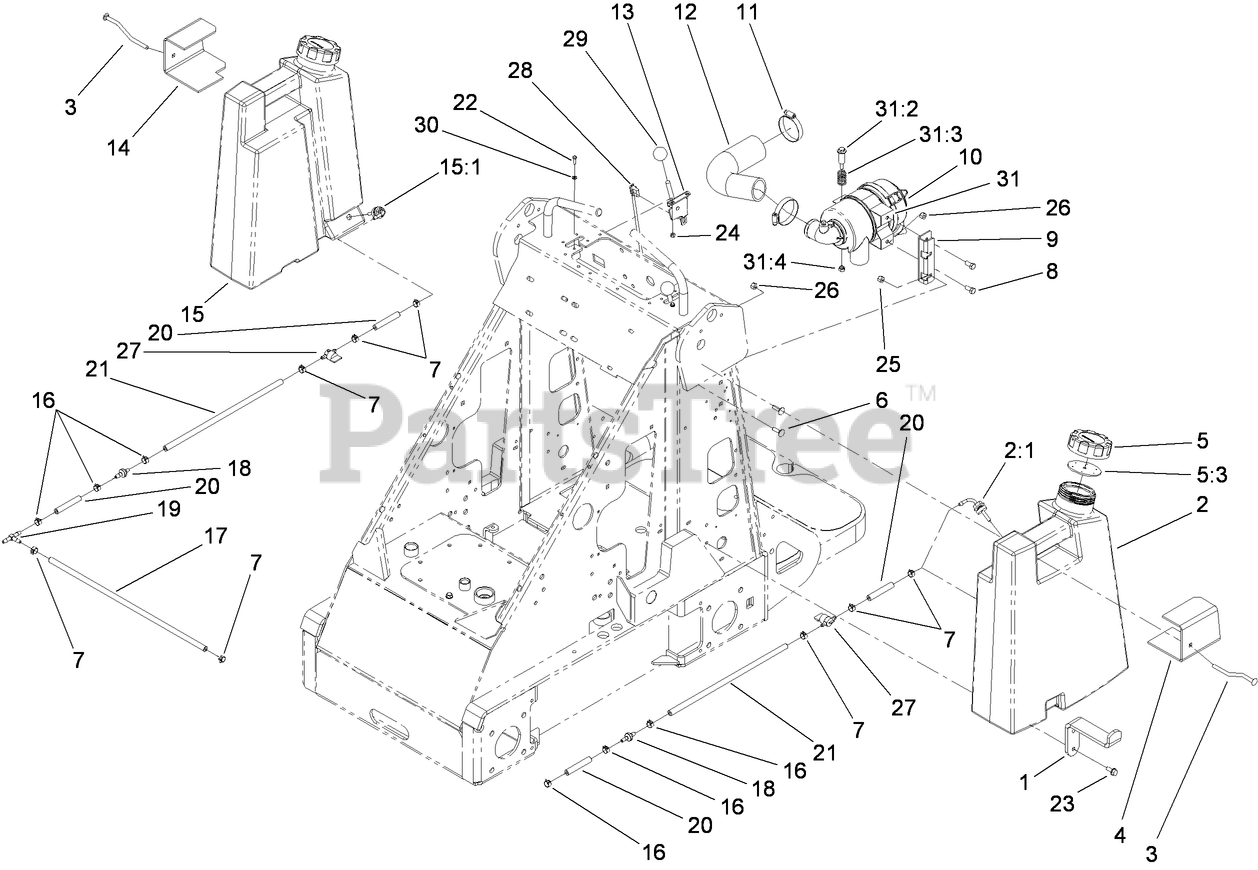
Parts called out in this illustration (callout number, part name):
1	MOUNT-BOTTOM, TANK
2	LH Fuel Tank ASM
2:1	FITTING-FUEL, BULKHEAD
3	BOLT-MOUNT
4	PLATE-MOUNT, LEFT
5	CAP-FUEL, GAS
5:3	GASKET-VENTED
6	BOLT-CARR
7	CLAMP-HOSE
8	SCREW-HH
9	MOUNT-CLEANER, AIR
10	AIR CLEANER ASM
11	CLAMP-HOSE
12	HOSE-AIR
13	LEVER-CONTROL
14	PLATE-MOUNT
15	RH Fuel Tank ASM
15:1	FITTING-FUEL, BULKHEAD
16	CLAMP-HOSE
17	HOSE-FUEL
18	VALVE-CHECK, FUEL
19	FITTING-TEE, BARBED
20	HOSE-FUEL
21	HOSE-FUEL
23	SCREW-HWHTF
24	NUT-KEPS
25	NUT-HF
26	NUT-LOCK, NI
27	VALVE-FUEL
28	CABLE-CONTROL
30	WASHER-FLAT
31	AIR CLEANER MOUNTING BAND ASM
31:3	SPRING
31:4	NUT
